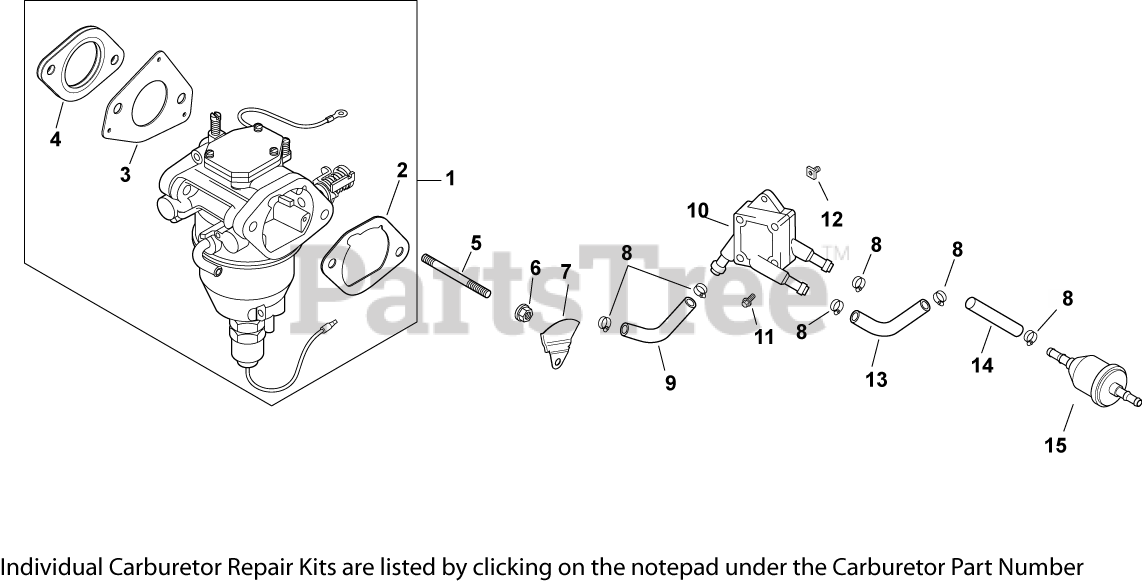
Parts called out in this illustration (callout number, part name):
1	KIT, CARBURETOR W/GASKETS
2	GASKET, AIR CLEANER BASE
3	GASKET, CARBURETOR
4	GASKET, CARBURETOR
5	STUD,M6X1.0X96
6	NUT, FLG M6X1.0
7	BAFFLE, SPIT-BACK CUP-USE 24 063 105-S
8	CLAMP, HOSE (KM)-USE 25 237 31-S
9	LINE, FLEXIBLE FUEL
10	PUMP, FUEL
11	SCREW, TAP M6X1.7X18
12	NUT, PLASTIC - BLACK
13	LINE, FUEL 11"
14	LINE - (#DSC)
15	FILTER,FUEL 51 MICRON (FUEL PUMP)
